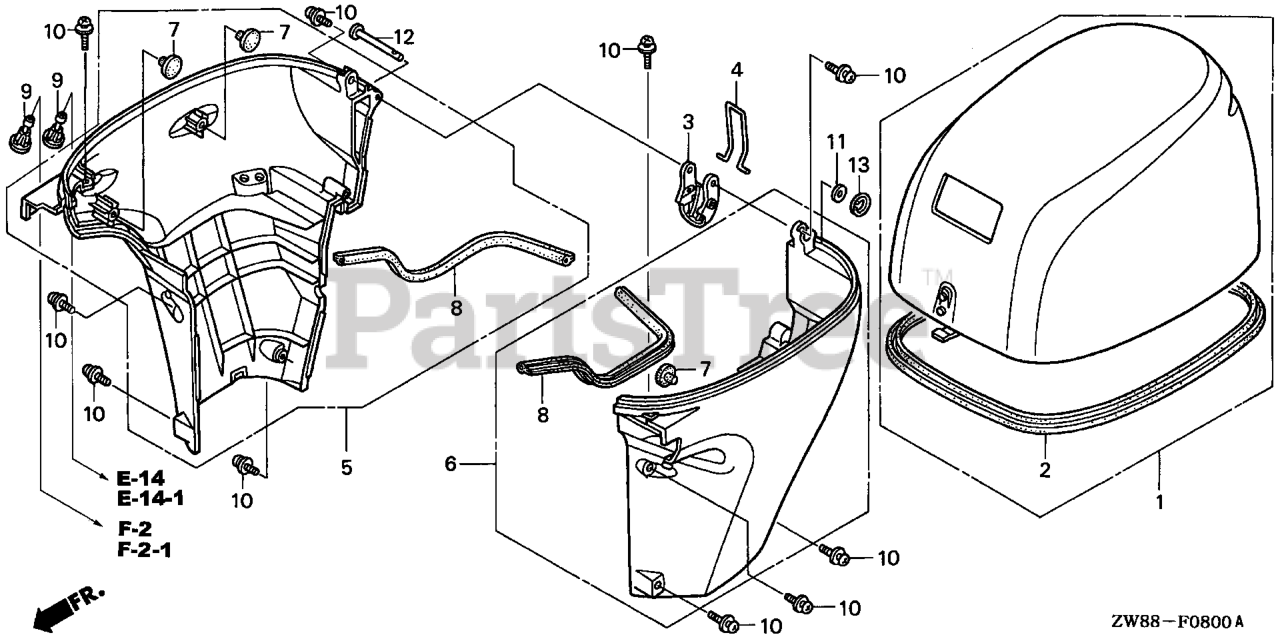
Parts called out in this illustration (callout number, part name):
1	COVER, ENGINE *NH282MU* (OYSTER SILVER METALLIC-U)
2	SEAL, ENGINE COVER
3	LEVER, FASTENER
4	WIRE, FASTENER (3.2)
5	COVER, R. ENGINE (LOWER) *NH282MU* (OYSTER SILVER METALLIC-U)
6	COVER, L. ENGINE (LOWER) *NH282MU* (OYSTER SILVER METALLIC-U)
7	RUBBER, CUSHION
8	SEAL, COVER (LOWER)
9	GROMMET, WATER CHECK
10	BOLT-WASHER, SOCKET (5X10)
11	WASHER, PLAIN (5MM)
12	PIN (5X47)
13	RING, STOPPER
